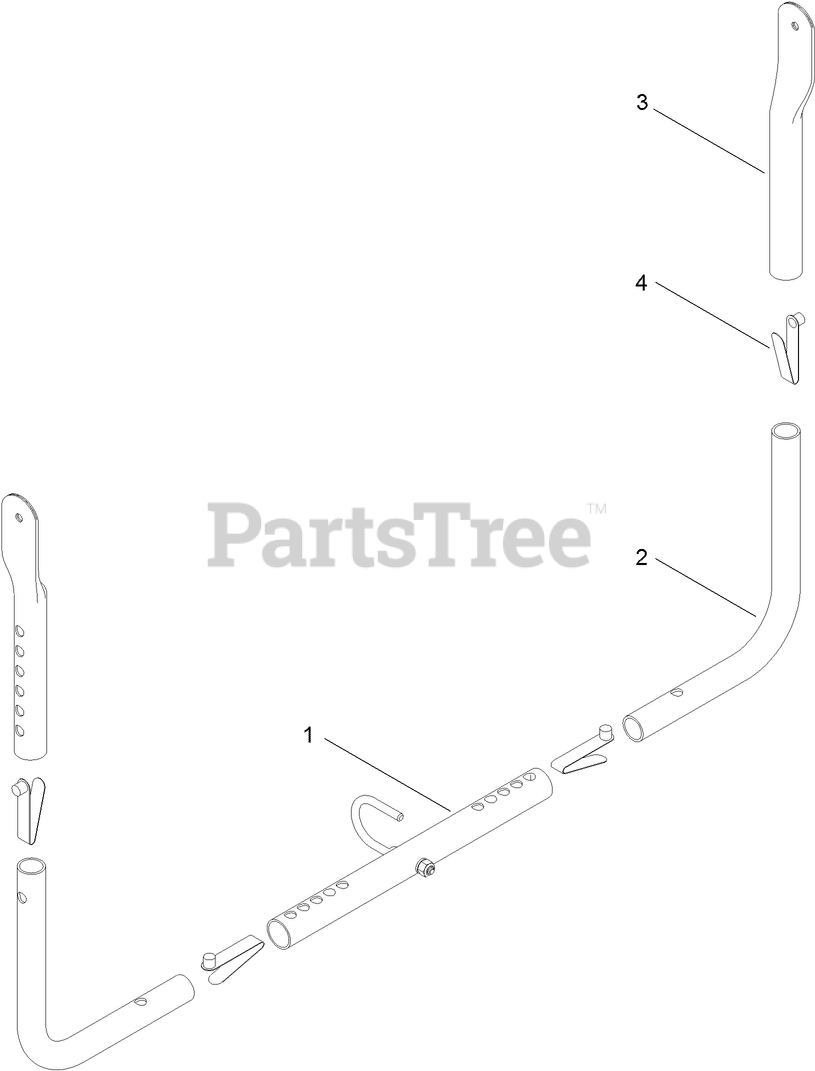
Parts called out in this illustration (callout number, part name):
1	HITCH TUBE ASM
2	TUBE-CORNER
3	TUBE-DOWN
4	BUTTON-SNAP, A STYLE
